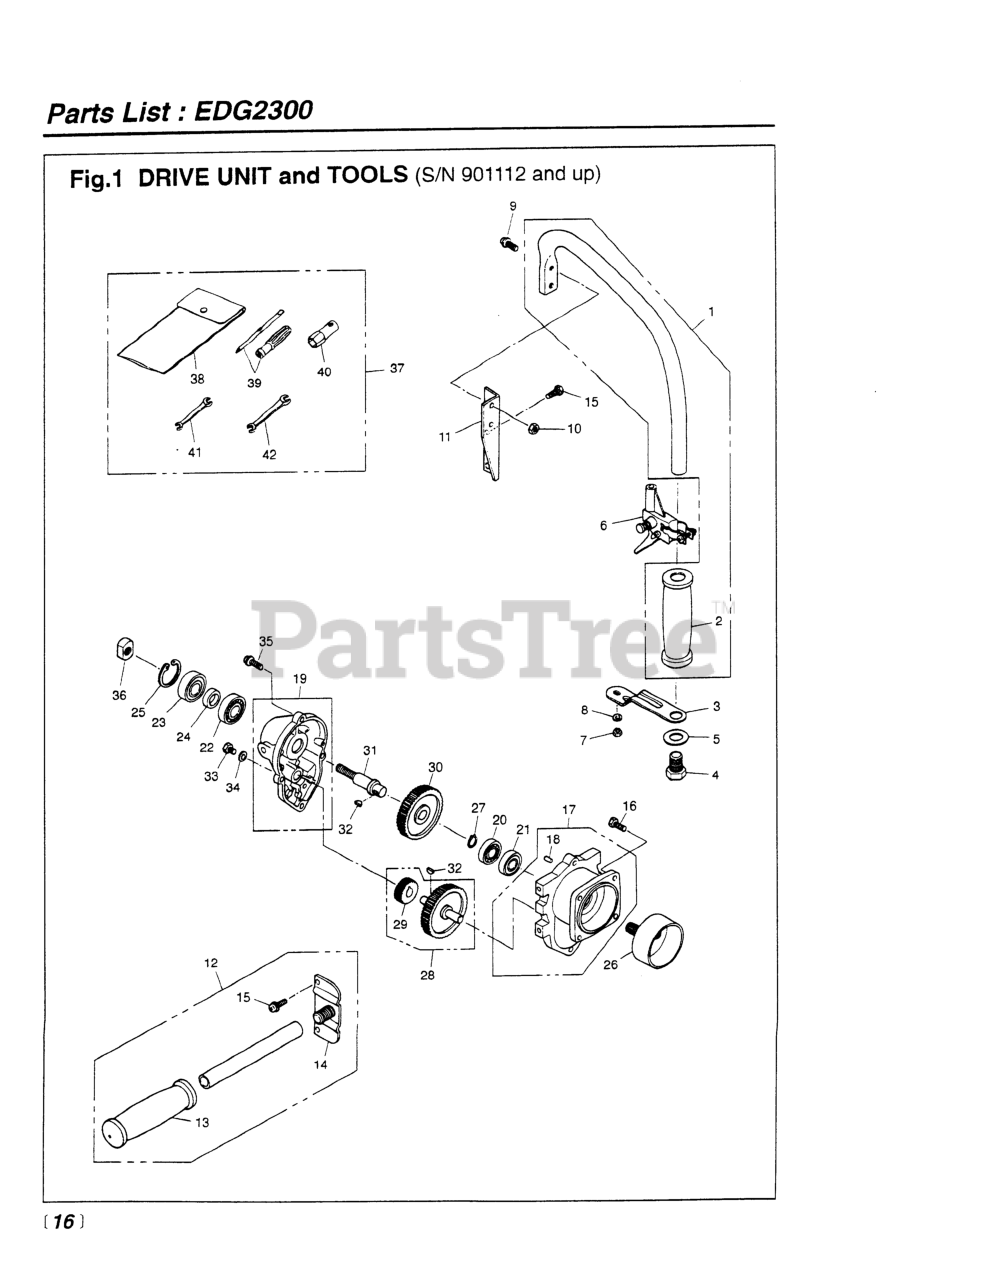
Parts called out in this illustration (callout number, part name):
1	HANDLE, RIGHT
3	STAY
5	WASHER, M14 x 2.3
6	LEVER, THROTTLE
7	NUT, M5 X 4
8	WASHER, SPRING M4 x 1.3
9	SCREW, M5 x 16
10	NUT, M5 X 4
11	BRACKET, RIGHT
12	HANDLE, LEFT COMP
13	GRIP (REPLACES -14220)
14	BRACKET, LEFT
15	BOLT, M6 x 16
16	BOLT, M6 x 16
17	CASE COMP, REAR HALF
18	PIN, DOWEL
19	CASE (B) (REPLACES -11200)
20	BEARING
25	RING, SNAP, M35 X 1.5
26	DRUM, CLUTCH
27	RING, SNAP (RPLS 3130-13270)
28	GEAR COMP, DRIVE(RPLS 13100)
29	GEAR, IDLER
30	GEAR, DRIVEN
31	SHAFT, PTO
32	KEY
33	BOLT, M6 x 10
34	WASHER, M6 X .8
35	BOLT M5 x 20 (RPLS -12280)
37	TOOL SET
39	SCREWDRIVER
40	SOCKET, HEX, 3/4
41	SPANNER, 8 X 10 (RPLS 2540- )
42	WRENCH (TOOL)
